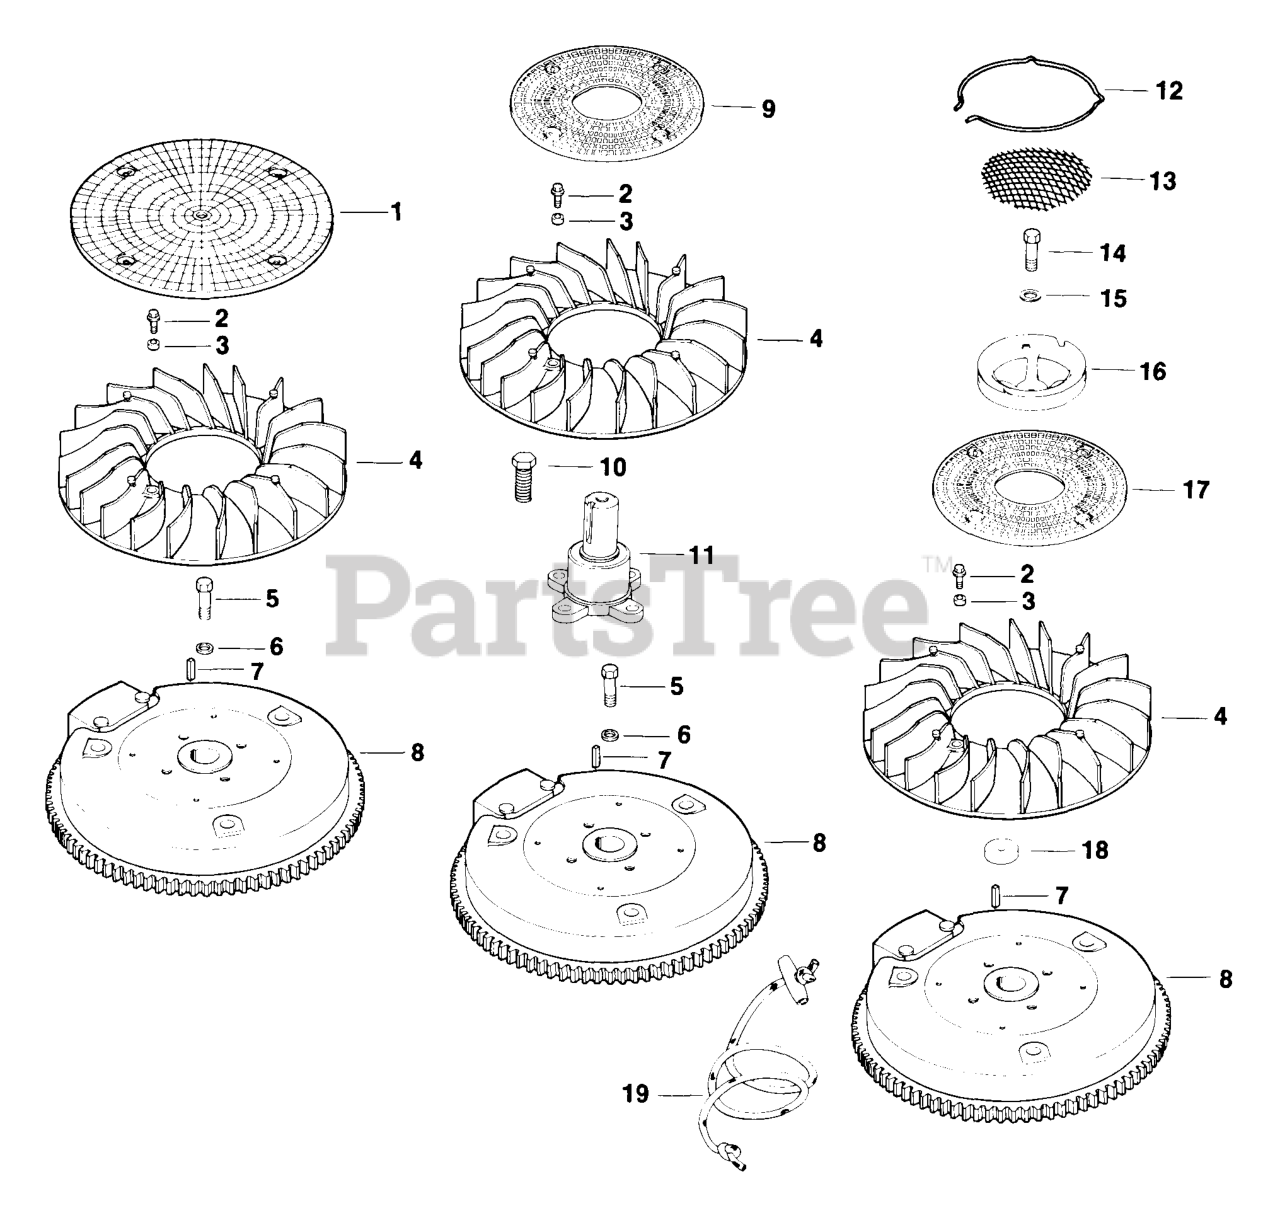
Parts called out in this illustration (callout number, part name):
2	Screw, Hex. Wash. Hd. 1/4-20x5/8"
3	Spacer 1/8"
5	Screw, Hex. Mach. 3/8-24x1-1/4"
6	Washer, Flat 3/8 I.D., 1-3/8 O.D. X 1/4"
7	Key, Square 3/16x7/8"
8	Flywheel
